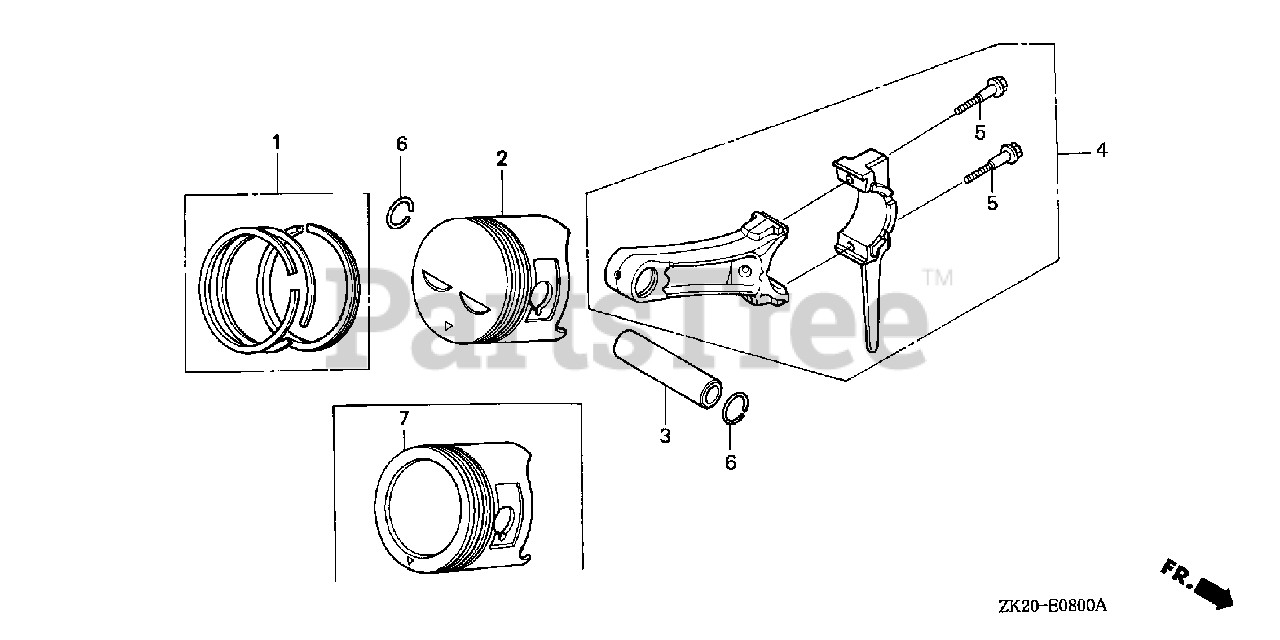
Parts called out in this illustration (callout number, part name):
1	RING SET, PISTON (STD)
1	RING SET, PISTON (STD) (TEIKOKU)
1	RING SET, PISTON (STD) (NIPPON)
1	RING SET, PISTON (OS 0.25)
1	RING SET, PISTON (OS 0.25) (TEIKOKU)
1	RING SET, PISTON (OS 0.25) (NIPPON)
1	RING SET, PISTON (OS 0.50)
1	RING SET, PISTON (OS 0.50) (TEIKOKU)
1	RING SET, PISTON (OS 0.50) (NIPPON)
1	RING SET, PISTON (0.75)
1	RING SET, PISTON (0.75) (TEIKOKU)
1	RING SET, PISTON (0.75) (NIPPON)
2	PISTON (STD)
2	PISTON (OS 0.25)
2	PISTON (OS 0.50)
2	PISTON (0.75)
3	PIN, PISTON
4	ROD ASSY., CONNECTING (STD)
4	ROD ASSY., CONNECTING (US 0.25)
5	BOLT, CONNECTING ROD
6	CLIP, PISTON PIN (18MM)
